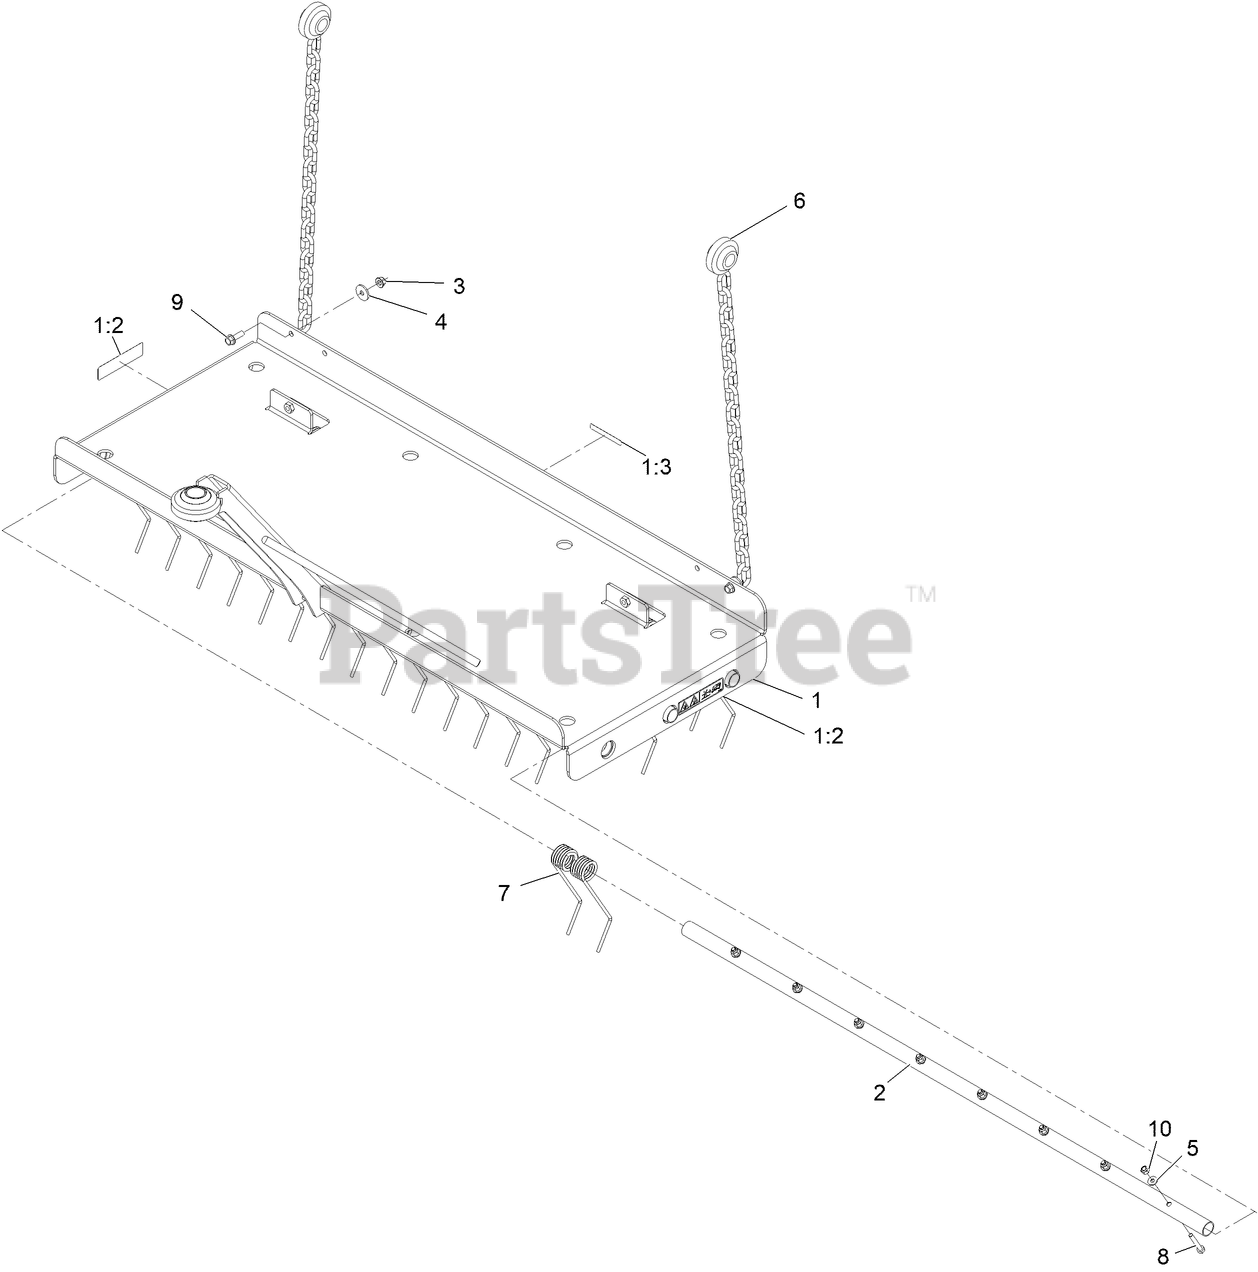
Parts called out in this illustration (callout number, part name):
1	Platfrom-Rake ASM W/Decals
1:2	DECAL-WARNING, TINES
1:3	DECAL-WARNING
2	RAKE TUBE
3	NUT-HF, NI
4	WASHER-FLAT
6	RAKE BALL SOCKET AND CHAI
7	SPRING TINE\NGG187DT-NB
8	SCREW-HH
9	SCREW-HH
10	NUT-LOCK, NI
